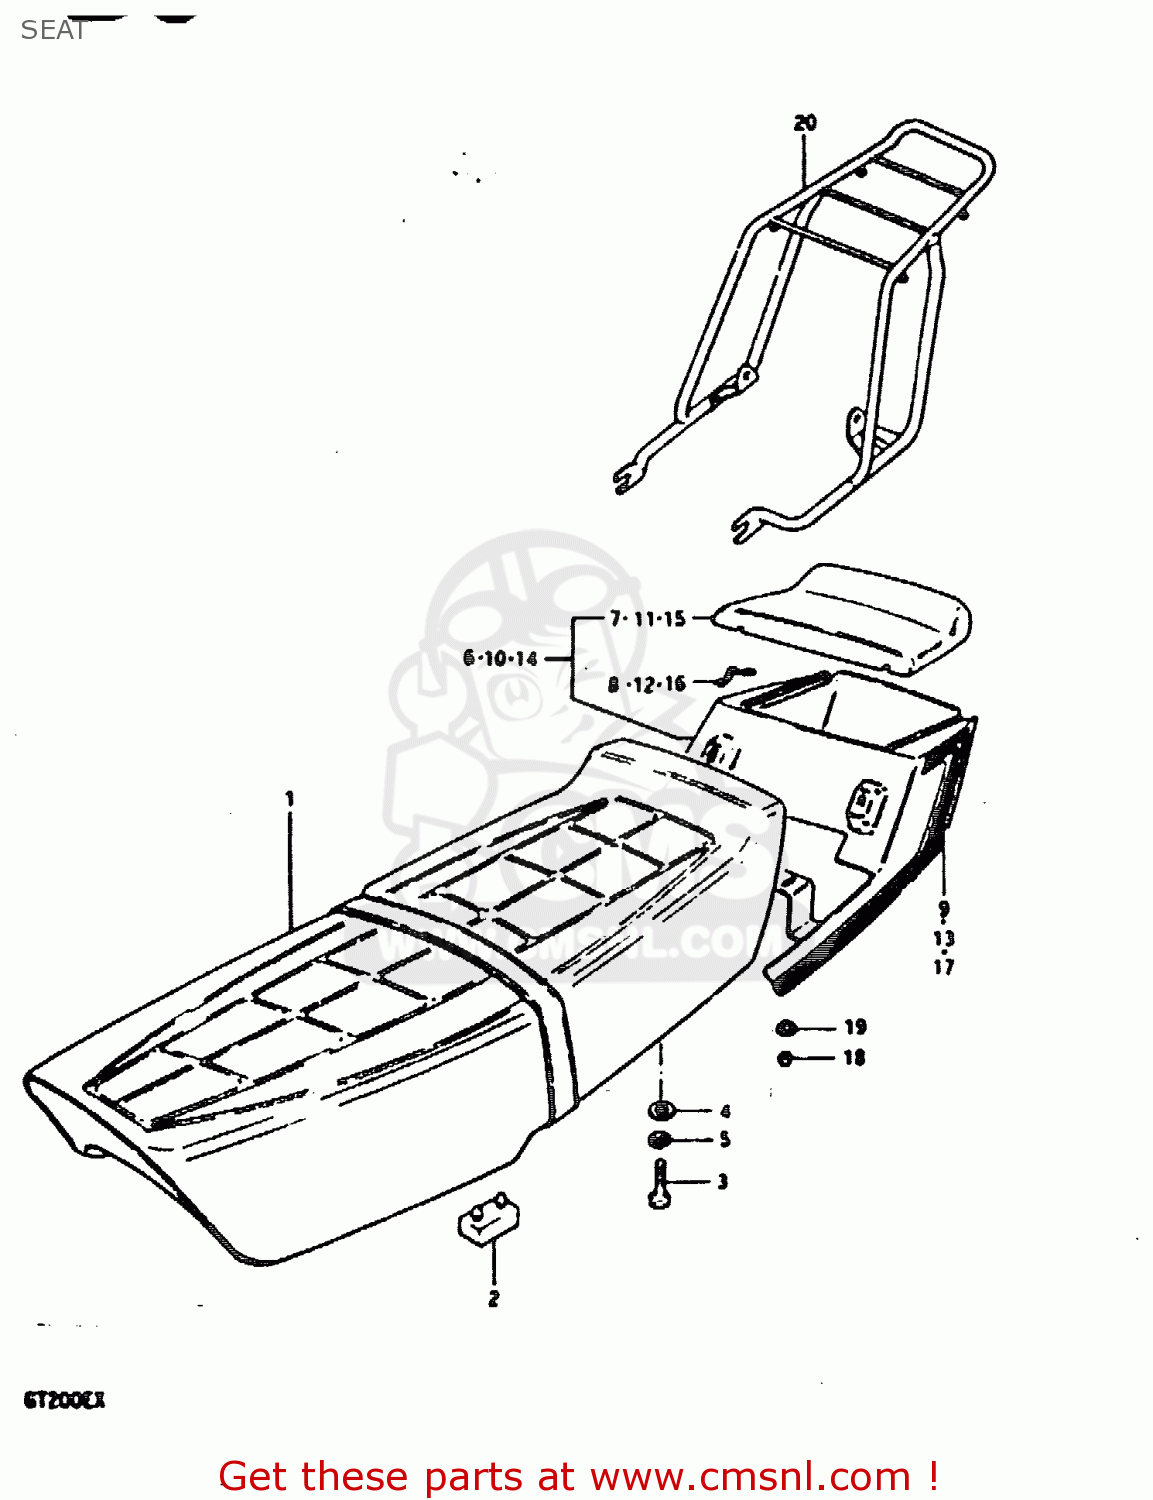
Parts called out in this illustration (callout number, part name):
1	SEAT (BLACK)
2	CUSHION
3	BOLT
4	WASHER (8.2X20X1.6)
5	LOCK WASHER
6	TAIL COVER, SEAT (WHITE)
7	LID, TAIL COVER (WHITE)
8	SPRING
9	TAPE SET
10	TAPE COVER, SEAT
11	LID, TAPE COVER
12	SPRING
13	TAPE SET
14	TAIL COVER, SEAT (RED)
15	LID, TAIL COVER (RED)
16	SPRING
17	TAPE SET
18	NUT 6MM
19	WASHER
20	CARRIER, SPORTS
